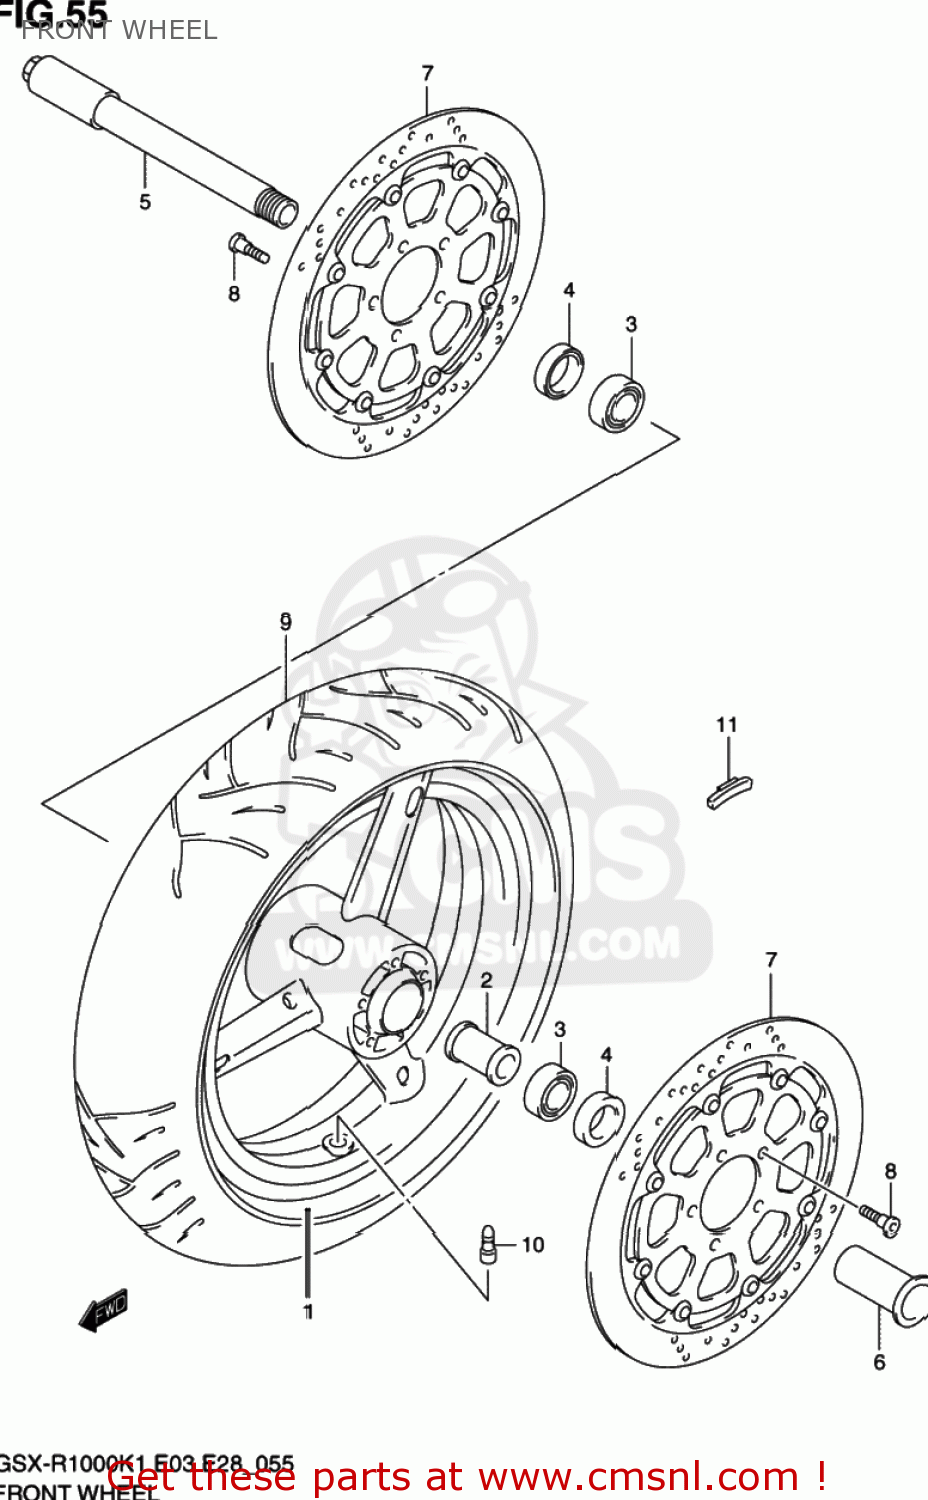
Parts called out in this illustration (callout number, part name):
1	WHEEL,FRONT (17XMT3.50)
2	SPACER,FRONT HUB BEARING
3	BEARING(25X52X15)
4	SEAL,OIL(32X52X7)
5	AXLE,FR
6	NUT,FR AXLE
7	DISC,FR BRAKE
8	BOLT(8X33)
9	TIRE, FRONT, 120/70ZR17 (58W)
10	VALVE ASSY,WHEEL RIM(TR412)
11	WEIGHT,BAL. 30
